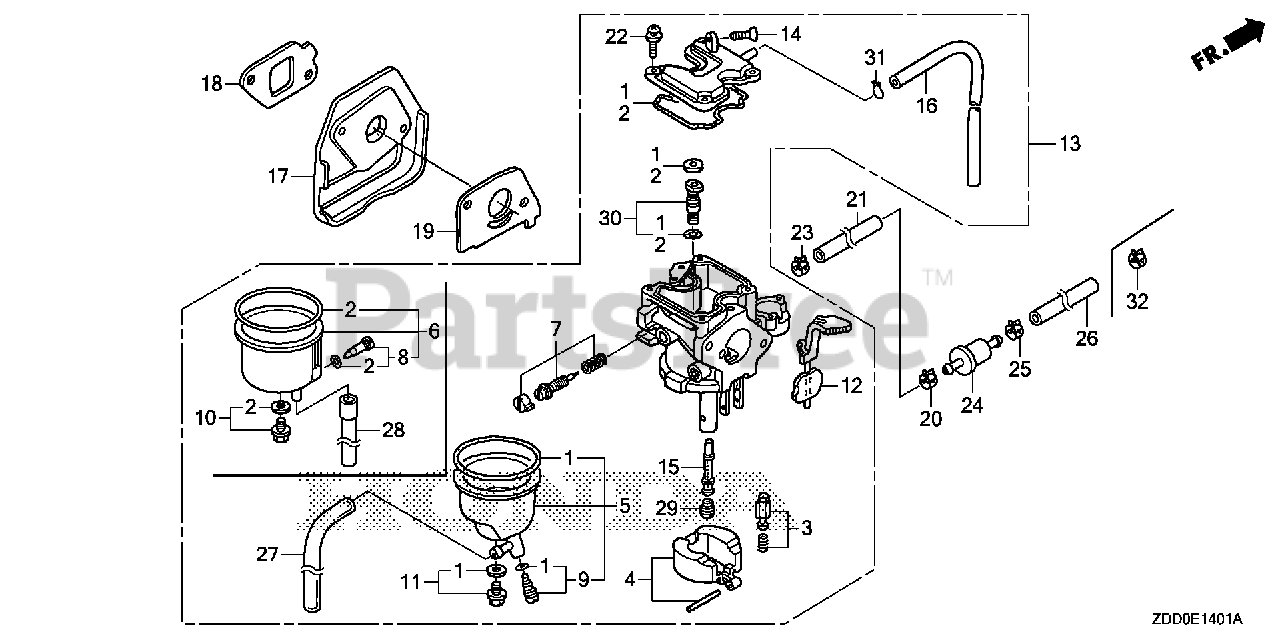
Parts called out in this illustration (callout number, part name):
2	GASKET SET (CARBURETOR NO.)
3	VALVE SET, FLOAT (CARBURETOR NO.)
6	CHAMBER SET, FLOAT (CARBURETOR NO.)
8	SCREW SET, DRAIN (ADVENTURE GREEN) (CARBURETOR NO.)
10	SCREW SET (CARBURETOR NO.)
12	LEVER SET, CHOKE
13	CARBURETOR ASSY. (BF34D A)
14	SCREW, THROTTLE STOP
15	NOZZLE, MAIN
16	TUBE, AIR VENT
17	INSULATOR, CARBURETOR
18	GASKET, INSULATOR
19	GASKET, CARBURETOR
20	CLIP, TUBE (D8.5)
21	HOSE, FUEL (4.2X160) (FKM)
22	SCREW-WASHER (4X12)
23	CLIP, TUBE (D8.5)
24	FILTER, FUEL
25	CLIP, TUBE (D8.5)
26	HOSE, FUEL (4.2X130) (FKM)
28	BULK HOSE, VINYL (3.5X6.5X8000) (9500(95003-05001-60M) (CARBURETOR NO.)
29	JET, MAIN (#52) Use from Engine SN BF12A B.
29	JET, MAIN (#55) Use from Engine SN BF22B D.
29	JET, MAIN (#58) Use from Engine SN BF22B D.
30	JET SET, PILOT (#35)
31	CLIP, TUBE (B1 8)
32	CLIP, TUBE (D8.5)
